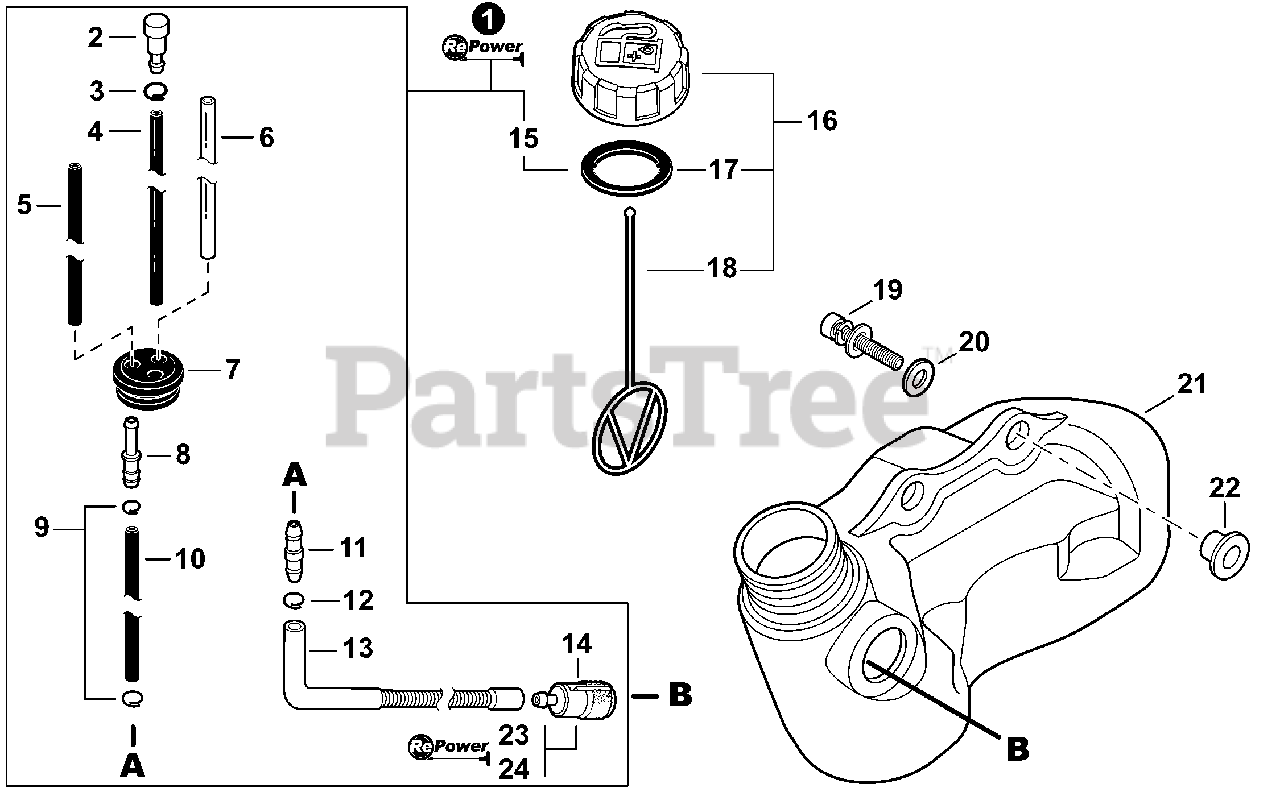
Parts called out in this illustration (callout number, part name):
1	FUEL SYSTEM KIT - REPOWER
2	VENT ASSY
3	CLIP Ø6
4	PIPE, FUEL 3×6×50 BLACK
5	PIPE, FUEL 3×5×61 BLACK
6	PIPE, FUEL 3×6×75 CLEAR
7	GROMMET, FUEL
8	CONNECTOR, PIPE Ø5ר3.5
9	CLIP Ø6.5MM
10	PIPE, FUEL 3×6×35 BLACK
11	CONNECTOR, PIPE
12	CLIP 6.6MM
13	PIPE, FUEL 3×7×100 FLEXIBLE
14	FILTER, FUEL
15	GASKET, FUEL CAP
16	CAP ASSY, FUEL
17	GASKET, FUEL CAP
18	CONNECTOR, CAP L= 123
19	BOLT 5×20
20	WASHER 5.5×12×0.8
21	TANK, FUEL
22	COLLAR 5
23	FILTER KIT - REPOWER
24	TUNE-UP KIT - REPOWER
